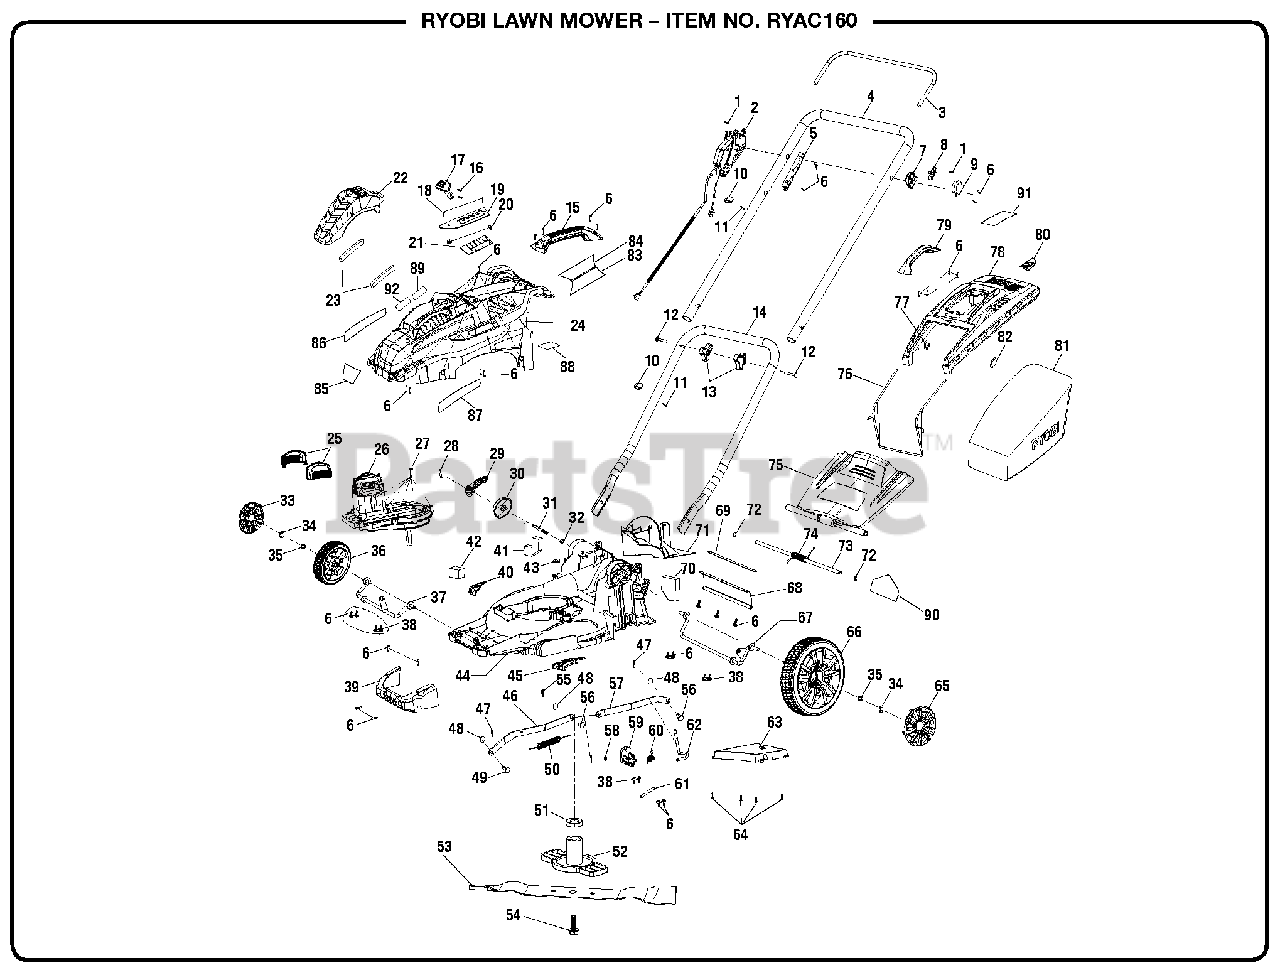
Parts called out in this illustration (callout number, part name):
1	Screw (M4 x 8 mm)
2	Control Box Assembly
3	Power Lever
4	Upper Handle Assembly
5	Lower Cover (Control Box Assembly)
6	Screw (M4.2 x 15 mm)
7	Bale Handle Cover (Right)
8	Bale Handle Holder
9	Bale Handle Cover (Left)
11	Screw w/Washer (M3 x 16 mm)
12	Bolt (M6 x 50 mm)
14	Lower Handle
16	Screw (M4 x 8)
17	Height Adjustment Handle
18	Screw (M5 x 12)
19	Height Adjustment Plate
21	Dust Gasket
22	Motor Cover
25	Dust Proof Motor Cover
27	Screw (M4.2 x 18 mm)
30	Base (Lock Handle)
31	Quick Lock Press
33	Front Wheel Cover
36	Front Wheel
37	Front Wheel Axle
38	Axle Pressure Plate
40	Grass Protector (Right)
45	Grass Protector (Left)
46	Front Lift Rod
48	Lock Pin Seat
50	Retention Spring
51	Bearing (6902RS)
52	Blade Holder
54	Bolt (M8 x 20 mm)
57	Rear Lift Rod
59	Height Adjustment Bracket
60	Spring (Height Adjustment)
61	Axle (Height Adjustment)
62	Height Adjustment Lever
64	Screw (M4.2 x 12 mm)
65	Rear Wheel Cover
67	Rear Wheel Axle
69	Rear Skirt Plate
71	Mulching Plug
73	Rear Door Axle
74	Torsion Spring (Rear Door)
75	Rear Discharge Door
77	Bag Cover Plug (Right)
80	Bag Indicator
82	Bag Cover Plug (Left)
83	Warning Label
84	Warning Icon Label
85	Logo Label
86	Feature Label
87	Feature Label
88	Single Point Adjustment Label
89	Data Label
90	Danger Label
91	Bagger Top Label
92	Danger Cord Warning Label
